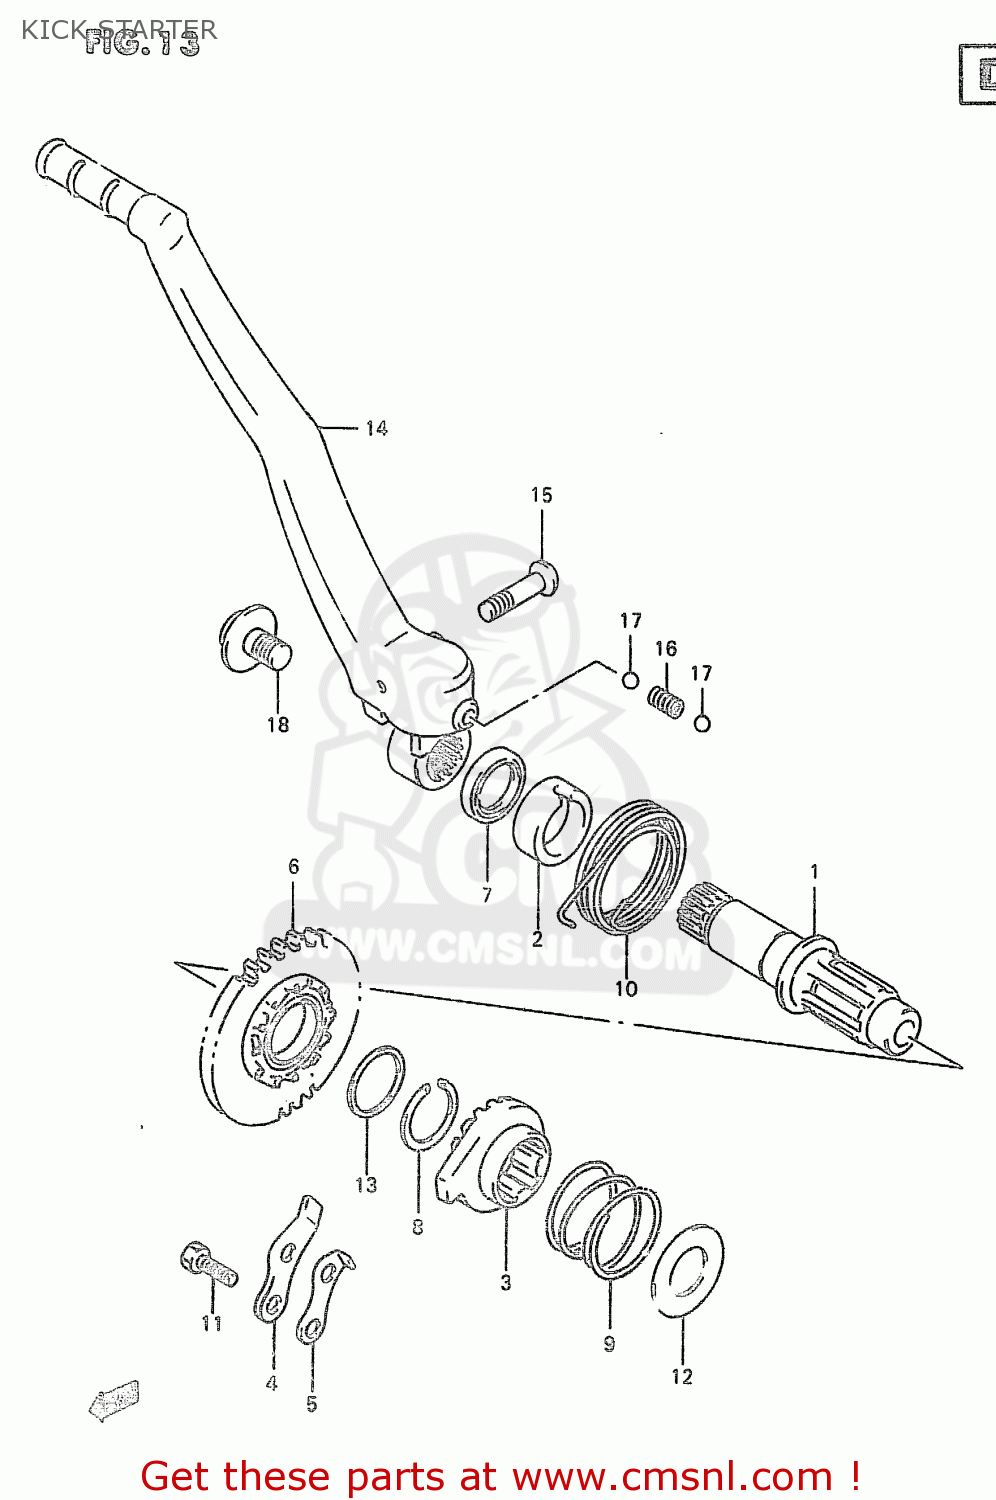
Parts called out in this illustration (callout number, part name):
1	SHAFT,KICK STARTER
2	GUIDE,KICK STARTER SHAFT
3	STARTER,KICK
4	GUIDE,KICK STARTER
5	STOPPER,KICK STARTER
6	GEAR,KICK STARTER DRIVE(NT:28)
7	SEAL,OIL(20X27X5)
8	CIRCLIP
9	SPRING
10	SPRING
11	BOLT
12	WASHER
13	SHIM
14	LEVER ASSEMBLY,KICK STARTER
15	SCREW(6X27.5)
16	SPRING
17	BALL
18	BOLT(8X14)
